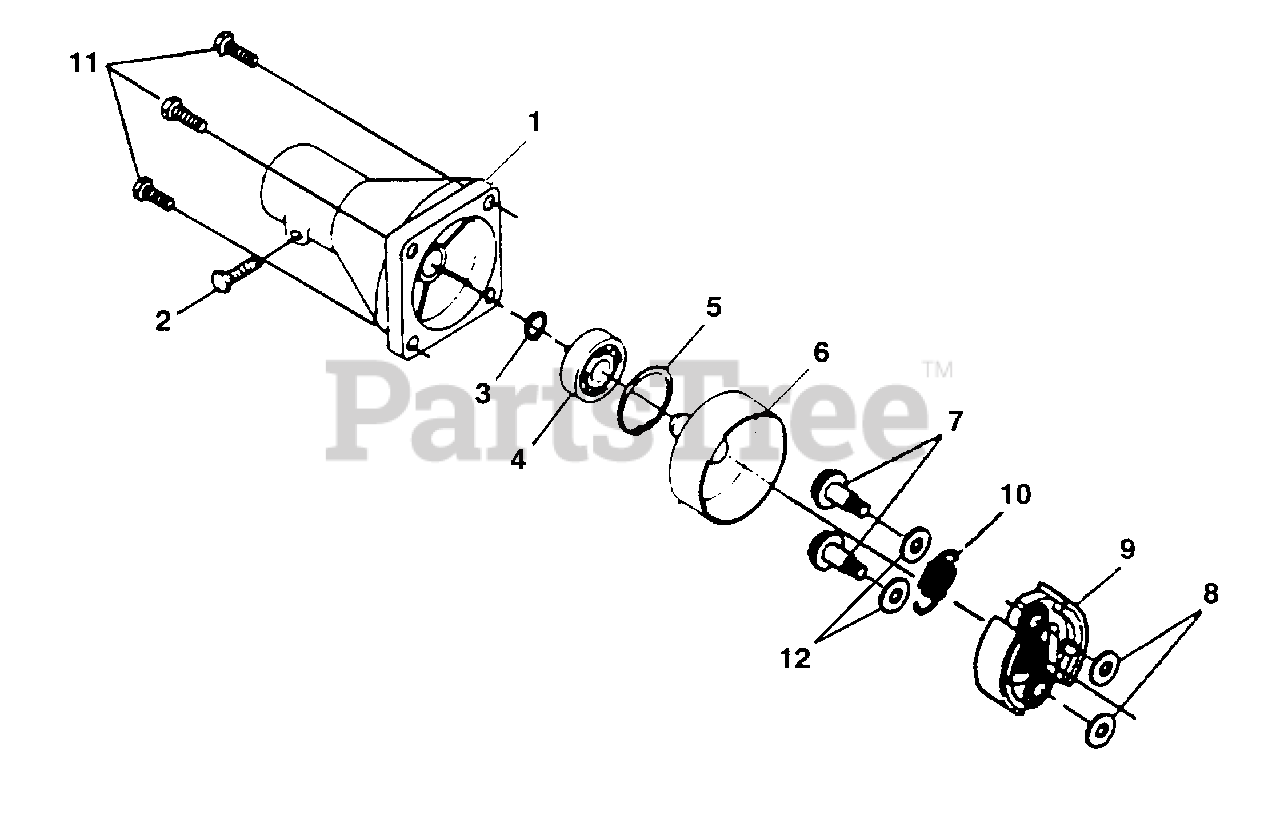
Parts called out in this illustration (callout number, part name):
1	CLUTCH CASE ASSY
2	BOLT & WASHER
3	SNAP RING
4	BALL BEARING
5	SNAP RING
6	CLUTCH DRUM
7	BOLT, CLUTCH
8	WASHER, CLUTCH
9	CLUTCH ASSY
10	SPRING, CLUTCH
11	BOLT & WASHER
